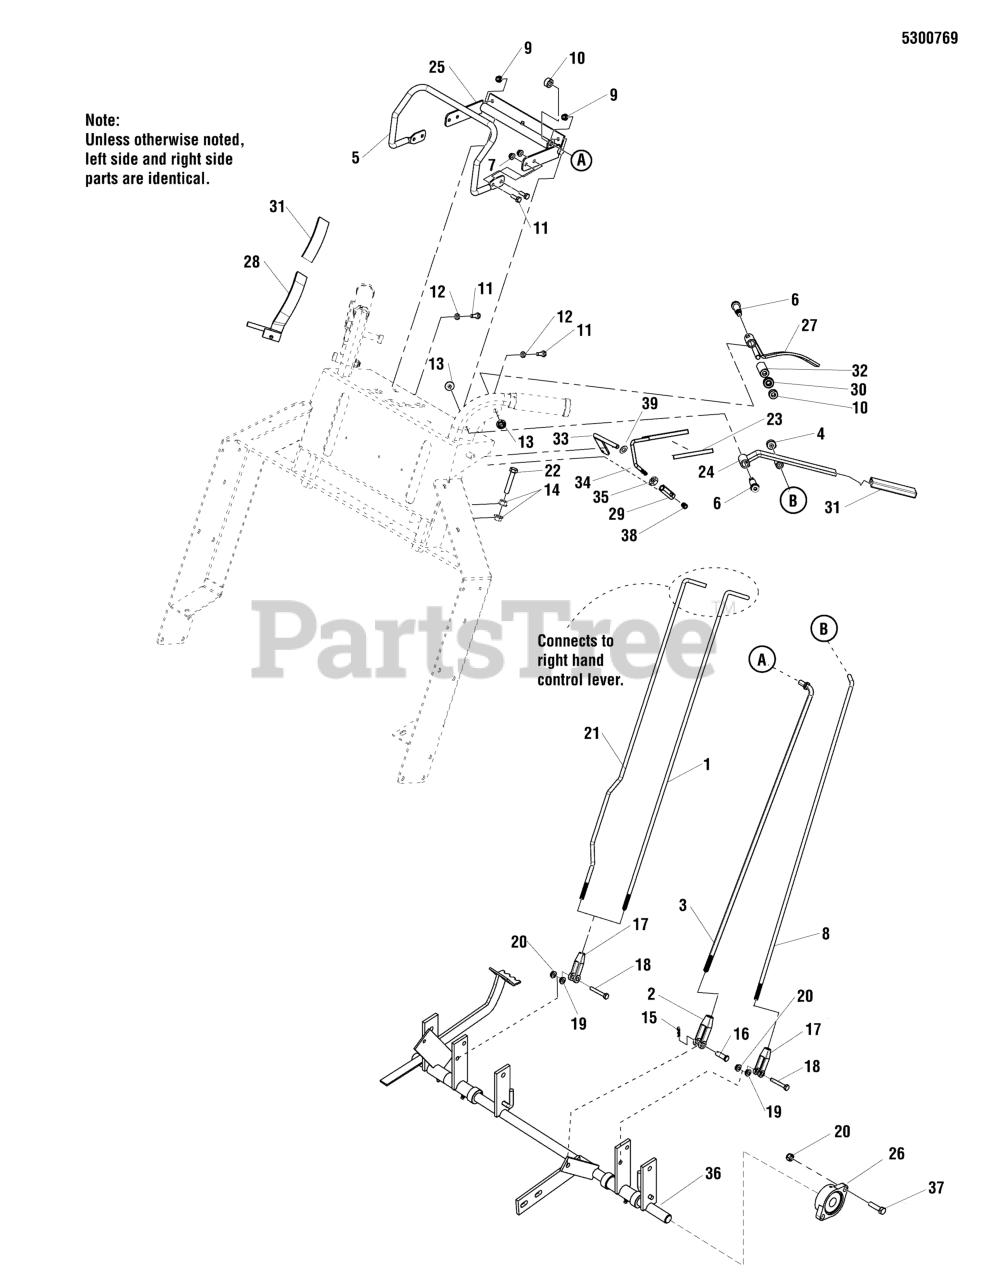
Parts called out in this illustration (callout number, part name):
1	ROD, DDS REVERSE CONTROL - RH
2	CLEVIS, 3/8-24, PLASTIC
3	ROD, CRUISE CONTROL W/WASHER
4	SET COLLAR, 5/16"
5	BAR, SPEED CONTROL - DUAL DRIVE
6	SHOULDER BOLT, 1/2" X 1-1/2"
7	NUT, 1/4-20 HEX NYLOCK FLANGE
8	ROD, DDS REVERSE CONTROL - LH
9	NUT, 1/4-20 HEX SERR. FLANGE
10	COLLAR, 3/8" SET
11	BOLT, 1/4-20 X 3/4" GD5
12	WASHER, 1/4 SAE
13	NUT, 3/8-16 HEX NYLOCK FLANGE
14	NUT, 3/8-16 HEX LG. SERR FLG
15	PIN, HAIR, .0585 X 1-1/8
16	PIN, CLEVIS, 3/8" X 1-1/8"
17	CLEVIS, 5/16-24, STEEL, CLEAR ZINC
18	BOLT, 5/16-18 X 2
19	NUT, 5/16-18 HEX
20	NUT, 5/16-18 HEX NYLOCK FLANGE
21	ROD, REVERSE - RH
22	BOLT, 3/8-16 X 1-3/4" TFL
23	GRIP, VINYL, 1/2 X 4"
24	WELD, HAND CONTROLS, DDS
25	WELD, SPEED CONTROL, DDS
26	BEARING, FLANGE
27	WELD, THUMB CONTROLS, DDS - LH
28	WELD, THUMB CONTROLS, DDS - RH
29	ADJUSTER, LINKAGE
30	BEARING, R6-2RS
31	GRIP, FOAM, 1/4 X 1 X 4.1
32	SPACER, .38 X .50 X 1.25, CZ
33	WELD, OPERATOR PRESENCE HANDLE
34	WELD, OPERATOR PRESENCE, OVERRIDE
35	NUT, 3/8-16 HEX
36	WELD, DDS CONTROL SHAFT
37	BOLT, 5/16-18 X 1" GD5 YZ
38	SET SCREW, 3/8-16 X 3/8
39	WASHER, 3/8 SAE
